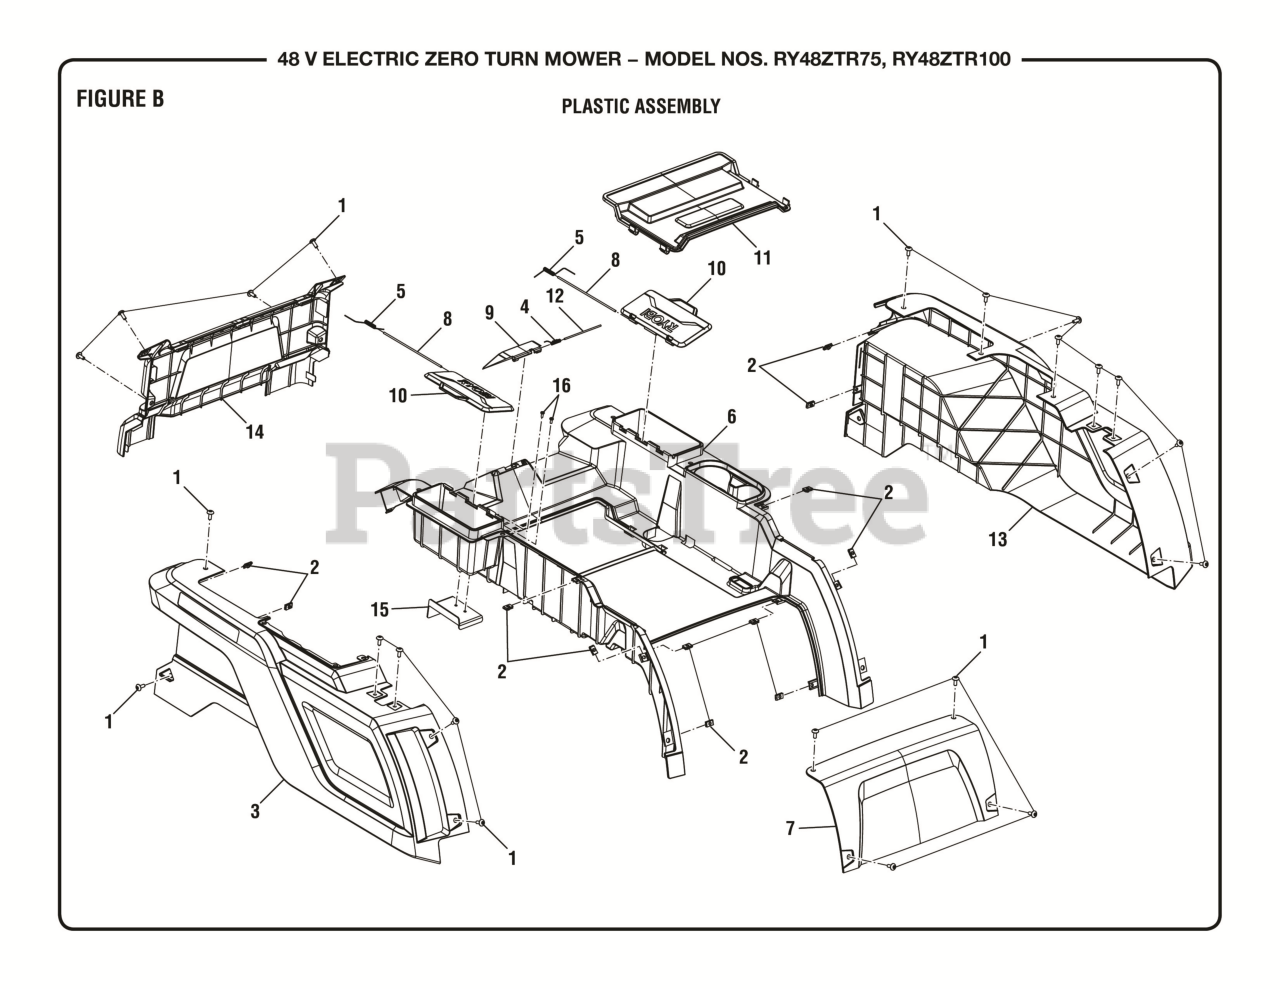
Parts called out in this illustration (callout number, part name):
1	Screw (M6 x 10 mm, Soc. Button Hd.)
2	Clip-On Nut (M6)
3	Right Trim Cover
4	Charger Port Door Spring
5	Storage Box Spring
6	Center Trim Cover
7	Front Access Panel
8	Storage Box Hinge Pin
9	Charger Port Door
10	Storage Box Lid
11	Center Access Panel
12	Charger Port Door Hinge Pin
13	Left Trim Cover
14	Rear Trim Cover
15	Main Relay Guard
16	Screw (M4 x 10 mm, Pan Hd.)
